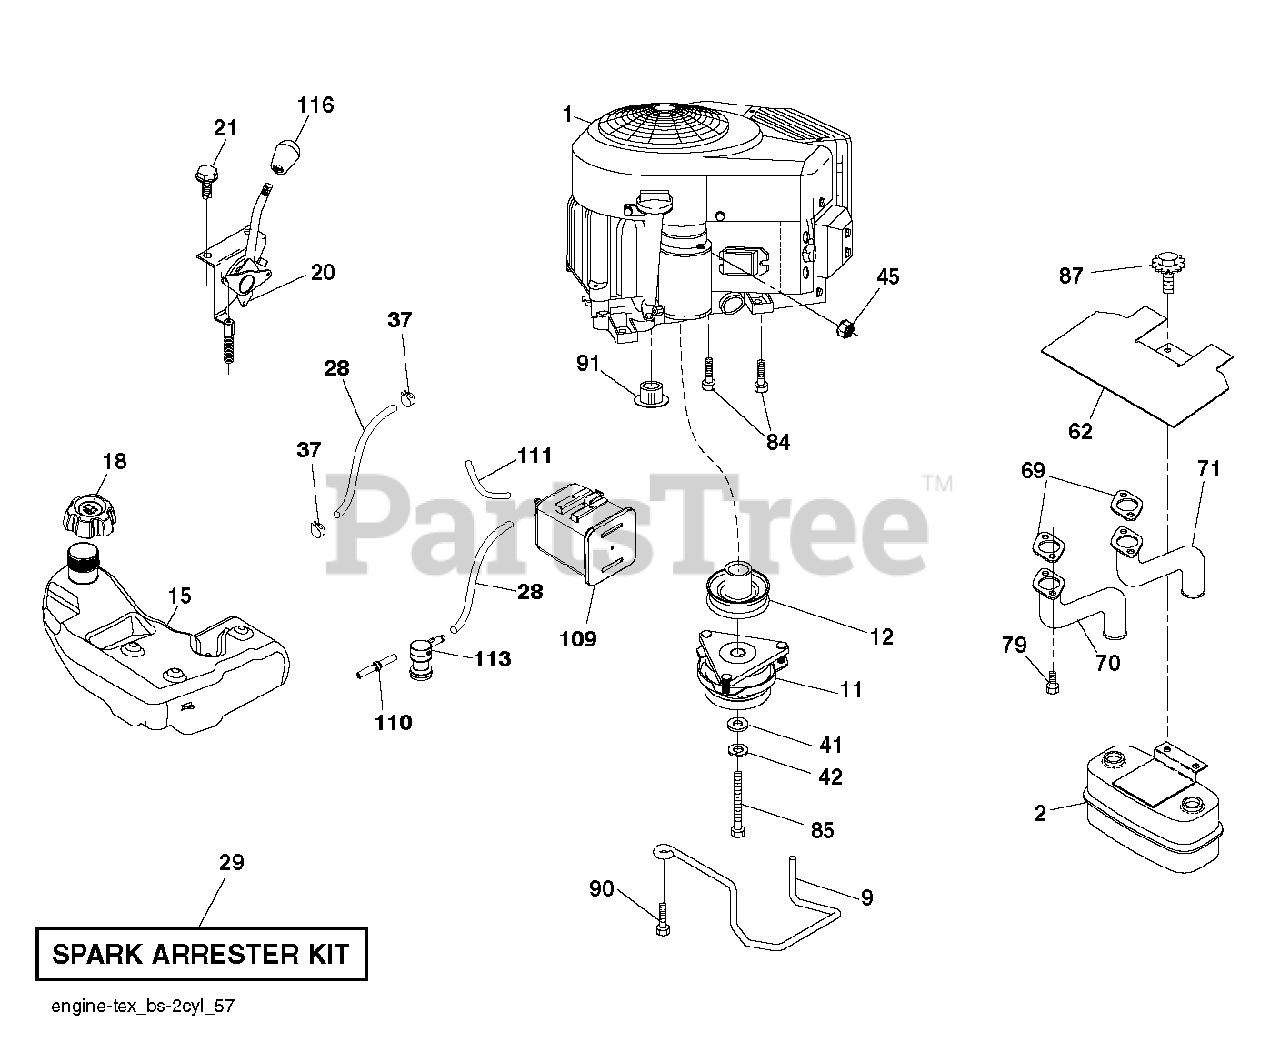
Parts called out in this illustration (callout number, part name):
2	MUFFLER.TWIN.CYL.LOW.TONE
9	KEEPER.BELT.ENGINE.4.2
11	CLUTCH.ELECTRIC.LT.48"*
12	PULLEY.ENGINE.TUFFTORQ
15	TANK.ASM.FUEL.3GA.CARB
18	CAP.ASM.FL.RITCH.3"E10.SYM.498
20	CONTROL THROTTLE/CHOKE
21	SCREW.#10 X 0.750.BOS
28	LINE.FUEL.64"REAR.EMIS
29	KIT.SPARK ARRESTOR 794945 B&S
37	HOSE CLAMP
42	LOCKWASHER
45	NUT
62	SHIELD.HEAT.MUFFLER
69	GASKET.MUFFLER
70	RP.EXHAUST.TUBE.LH.BS/TWIN
71	EXHAUST.TUBE.RH.BS/TWIN
79	SCREW.SOCKET.HEAD.5/16-18
84	SCREW.3/8-16
85	BOLT HEX 7/16-20X4-1/4"
87	Bolt, 5/16-18 X 1-3/4
90	SCREW 3/8-16X1
91	BUSHING.1.375OD
109	CANNISTER, CARBON
110	VALVE.ASM.ANTI-SLOSH
111	RP PURGE LINE
113	VALVE.SLANT.CARTRDG.90 DEG.TEX
116	RP KNOB SOFT TOUCH
